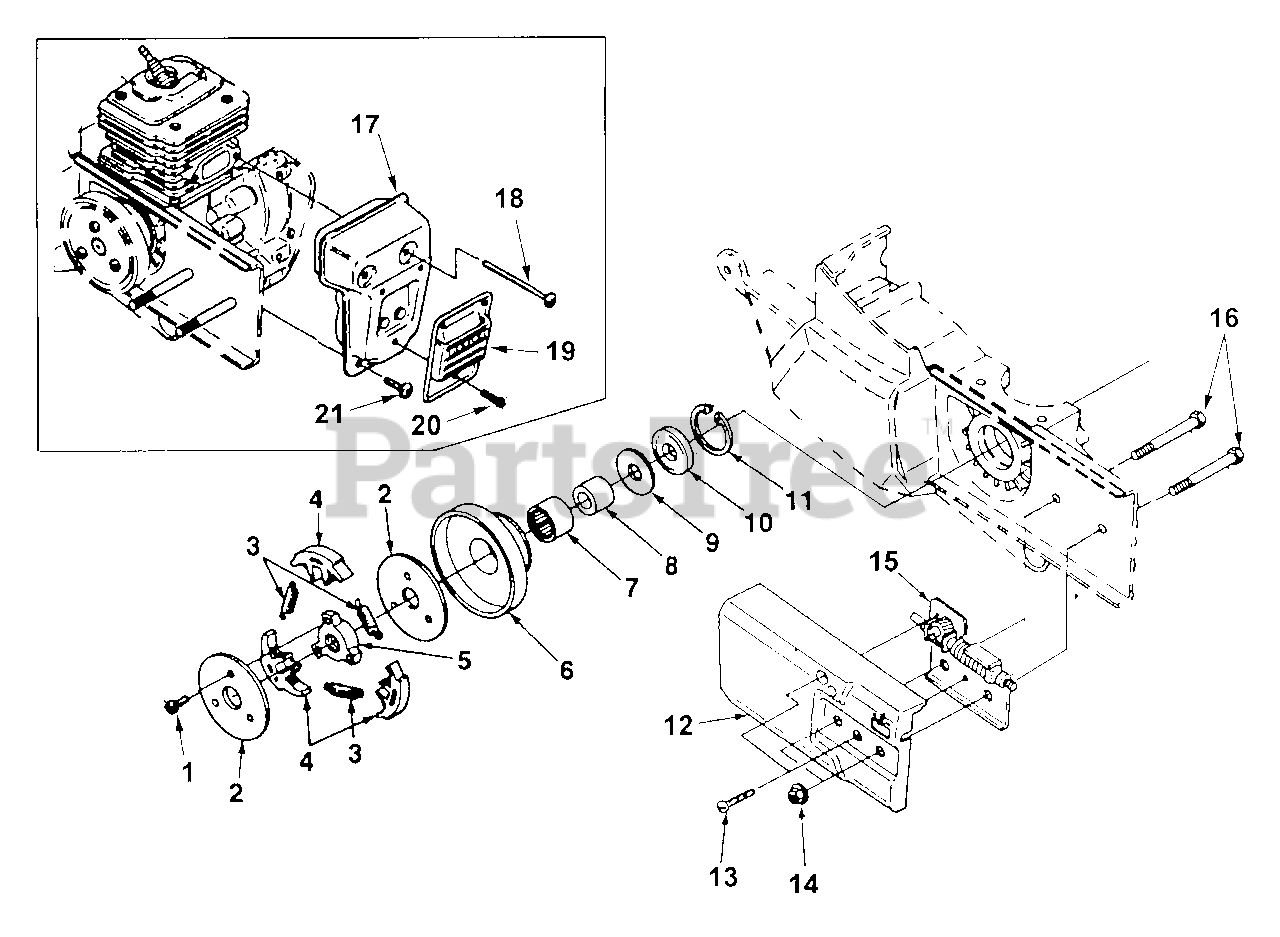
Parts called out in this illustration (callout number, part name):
1	SCREW - Machine Hex Hd (8-32 x 3/8")
2	COVER - Clutch
3	SPRING - Clutch
4	SHOE - Clutch
5	CLUTCH - Spider
6	PULLEY - Drum & Bearing
7	BEARING - Needle
8	RACE - Inner
9	WASHER - Thrust
10	SEAL - Main
11	RETAINER - Bearing
12	CLUTCH - Cover
13	SCREW - Taptite (8-32 x 5/8")
14	NUT - Hex Flange (5/16-18)
15	GEAR KIT
16	BOLT - Wheel Arm
17	MUFFLER
18	SCREW - Truss Hd (10-24 x 2 1/2")
19	CAP - Muffler
20	SCREW - Machine Hex Hd (8-32 x 1/2")
21	SCREW - Torx (10-24 x 1/2")
